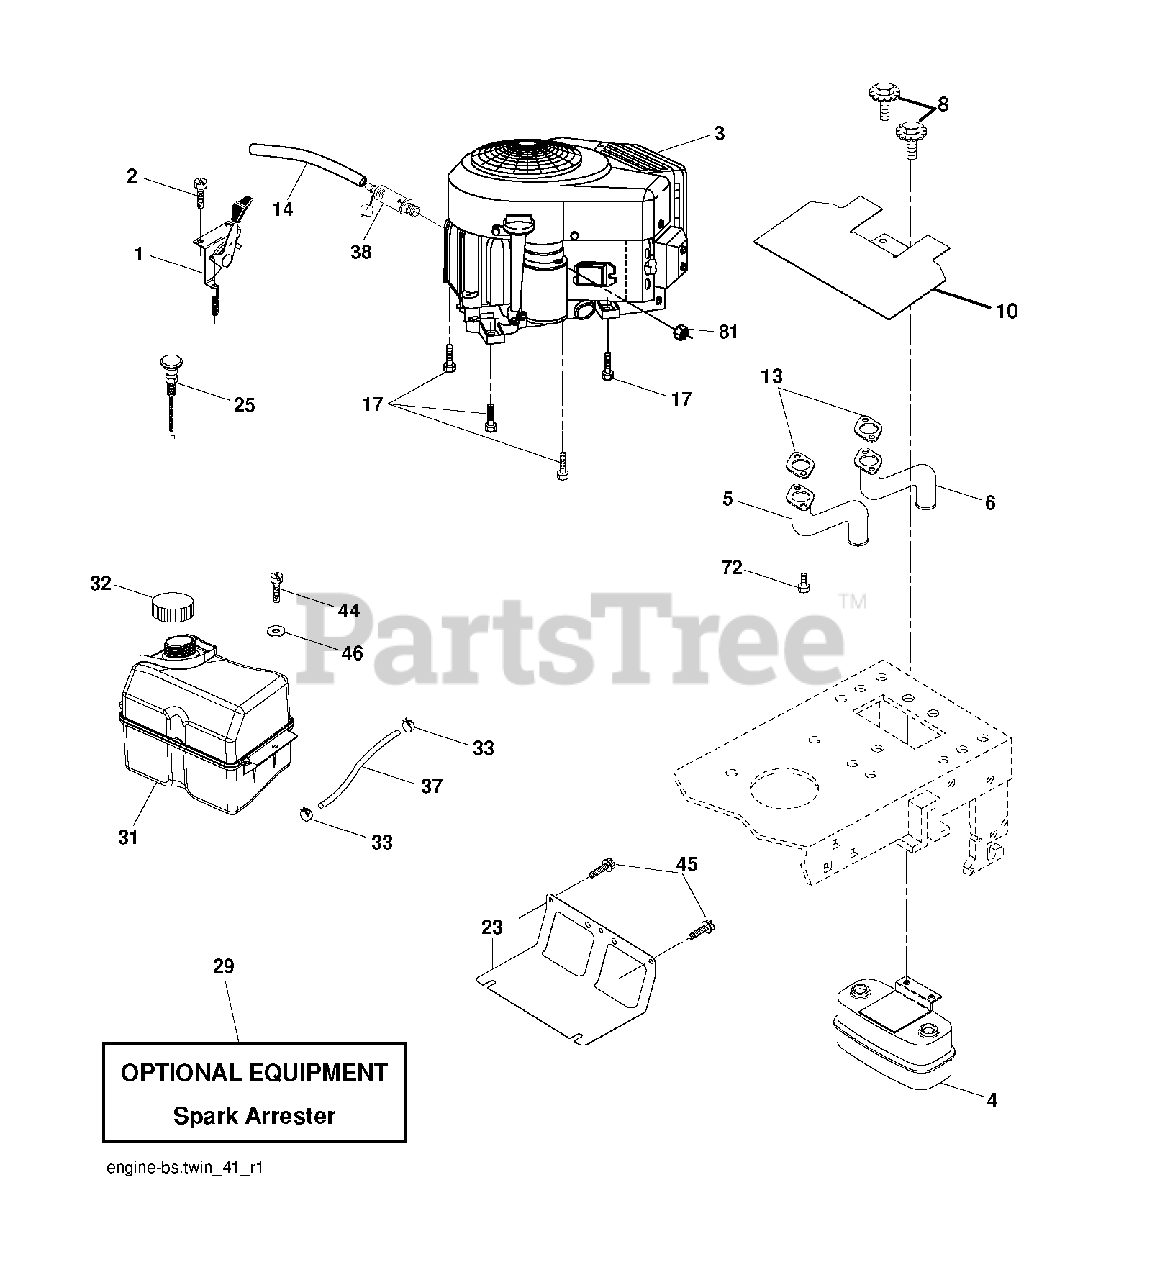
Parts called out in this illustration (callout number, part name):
1	THROTTLE CABLE
2	SCREW
4	MUFFLER.TWIN.CYL.LOW.TONE
5	EXHAUST TUBE RH
6	TUBE MANIFOLD LH
8	BOLT, 5/16-18 X 1 3/4
10	RP SHIELD HEAT MUFFLER
13	GASKET.MUFFLER
14	TUBE, DRAIN OIL ASM.
17	SCREW.3/8-16
23	SHEILD.BROWNING.DBR.GUARD
25	CONTROL CHOKE
29	ARRESTER SPARK (OPTIONAL)
31	TANK FUEL
32	FUEL CAP
33	HOSE CLAMP
37	LINE.FUEL.20
38	PLUG DRAIN OIL EASY
44	SCREW HEXWSHR 1/4-20X3/4
45	SCREW, 3/8-16X3/4
46	WASHER
72	SCREW.SOCKET.HEAD.5/16-18
81	NUT
